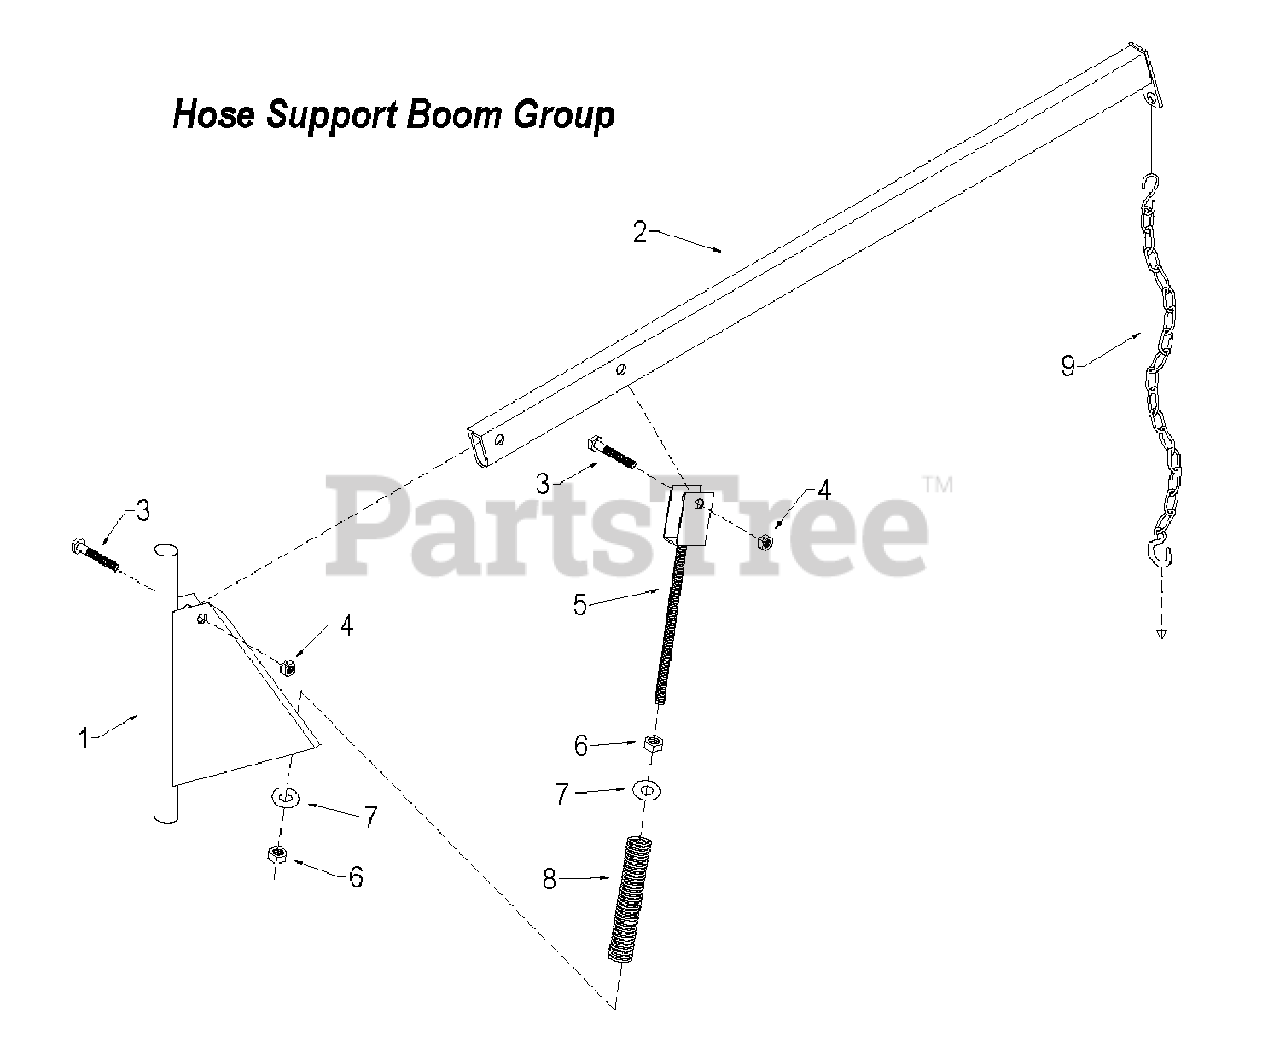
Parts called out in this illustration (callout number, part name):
1	Boom vertical member
2	Boom horizontal member
3	Bolt, hex – 1/2-13 x 3"
4	Nut, reverse lock – 1/2-13
5	Guide, threaded spring
6	Nut, hex – 3/4-10
7	Washer, flat – 3/4"
8	Spring, boom
9	Chain, boom – 48 w/2 S-hooks
